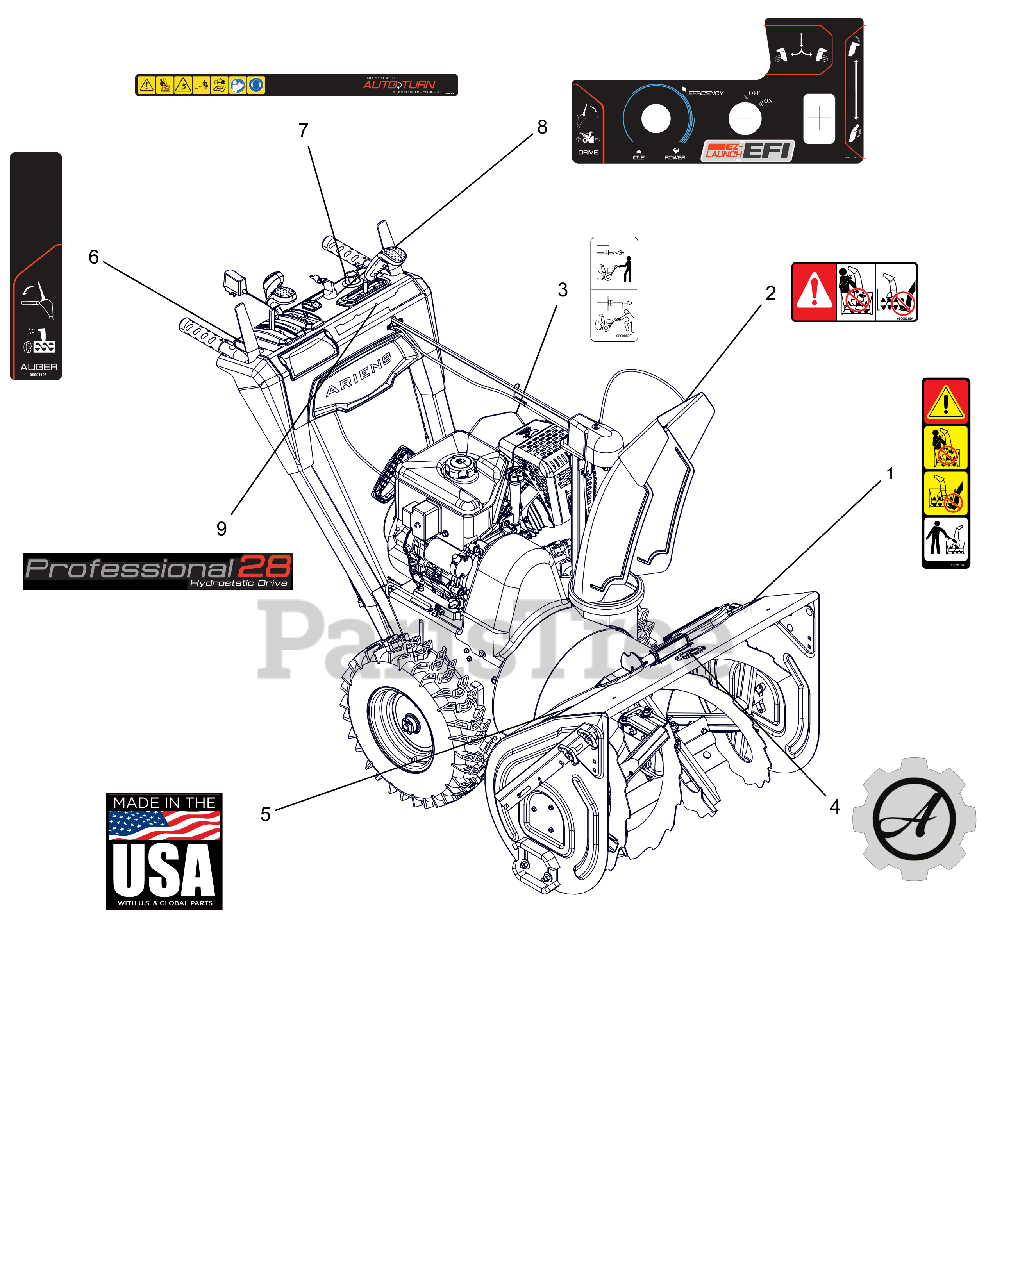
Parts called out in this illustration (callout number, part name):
1	DECAL, DANGER - ROTATING PARTS
2	DECAL, DANGER
3	DECAL, BYPASS
4	DECAL, ARIENS-GEAR BADGE -THK
5	DECAL, MADE IN USA
6	DECAL,CONTROL-RH CONTROL
7	DECAL,DASH - SAFETY/EFI
8	DECAL, CONTROL - QT EFI W/GEL
9	DECAL, DASH - PRO HYDRO 28
